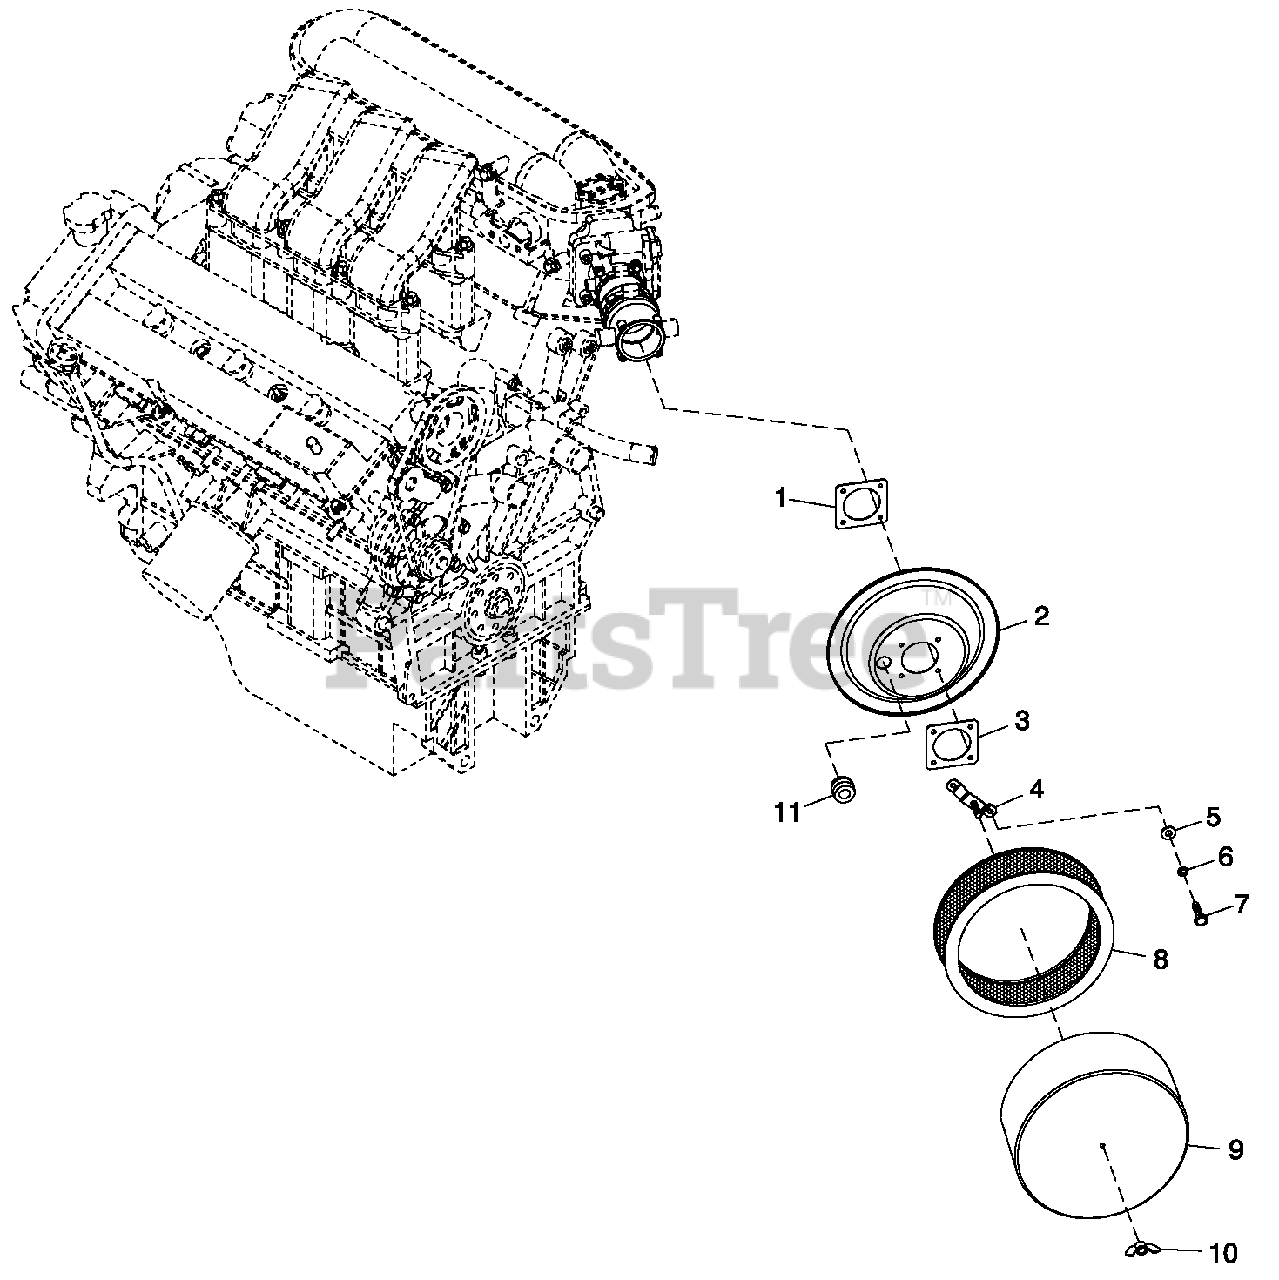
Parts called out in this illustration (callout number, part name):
1	GASKET, MIXER BODY
2	BASE PLATE AIR CLEANER
3	TOP PLATE VENTURI
4	HOLD DOWN AIR CLEANER
5	WASHER FLAT M6
6	WASHER LOCK M6-1/4
7	SCREW HHC M6-1.0 X 16 G8.8
8	ELEMENT AIR FILTER
9	PLATE, AIR CLEANER TOP
10	NUT WING 1/4-20 NYLK
11	GROMMET 7/8 X 1/16 X 3/4
